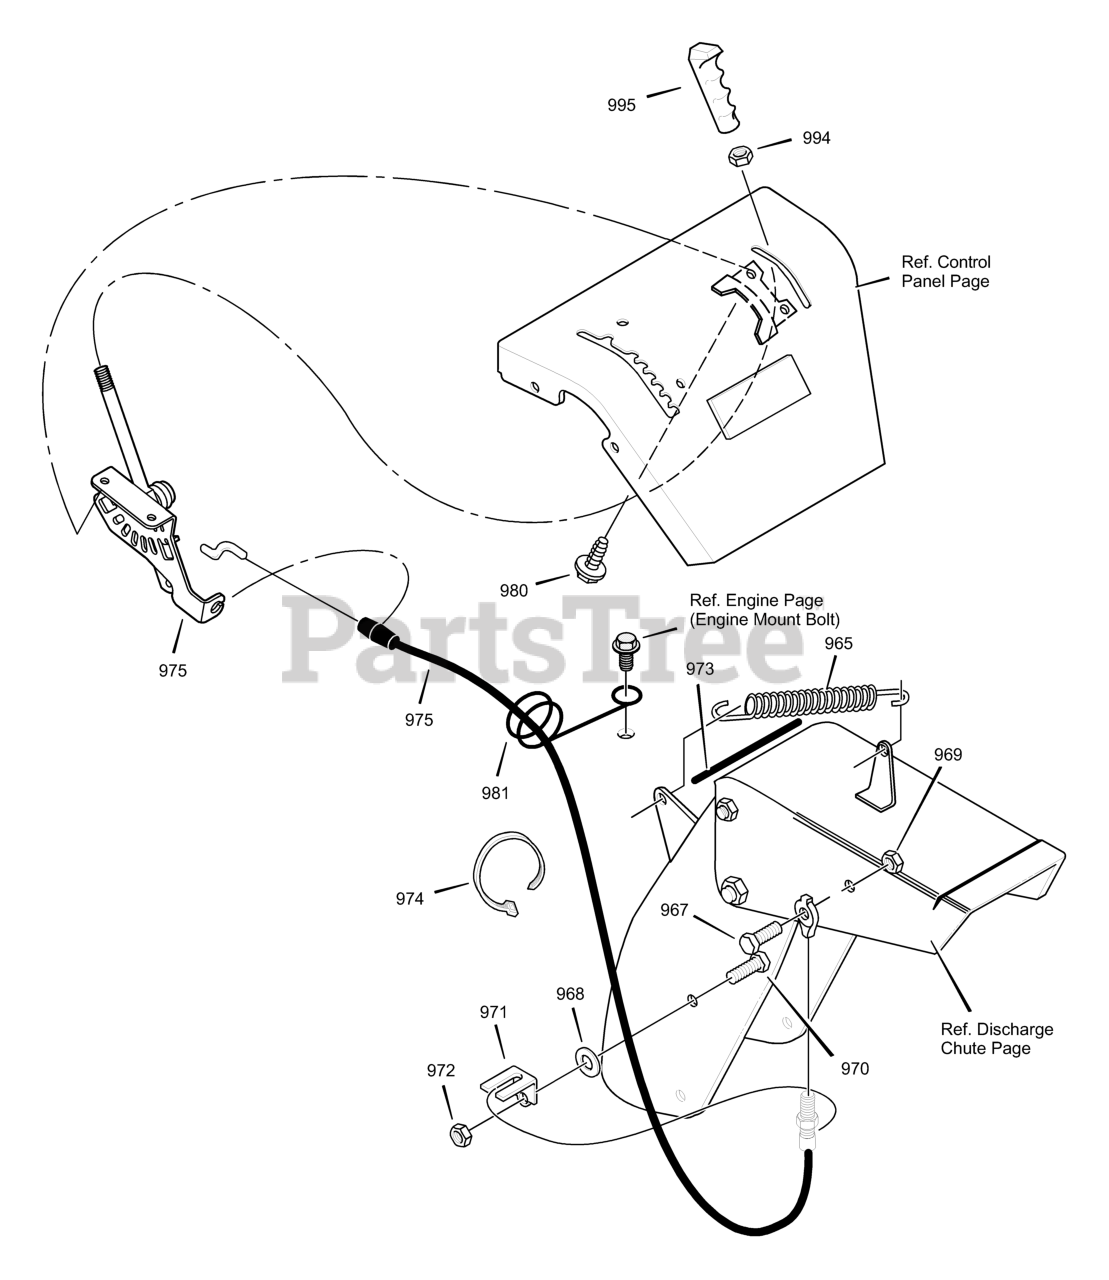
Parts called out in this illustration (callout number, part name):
965	TENSION SPRING
968	FLATWASHER
971	BRACKET, CABLE CHUTE
972	NUT
973	TRIM STRIP
974	TIE, CABLE
975	ASSY, CHUTE DEF. CONTROL
980	SCREW
981	WIRE FORM, REMOTE CHUTE CABLE
